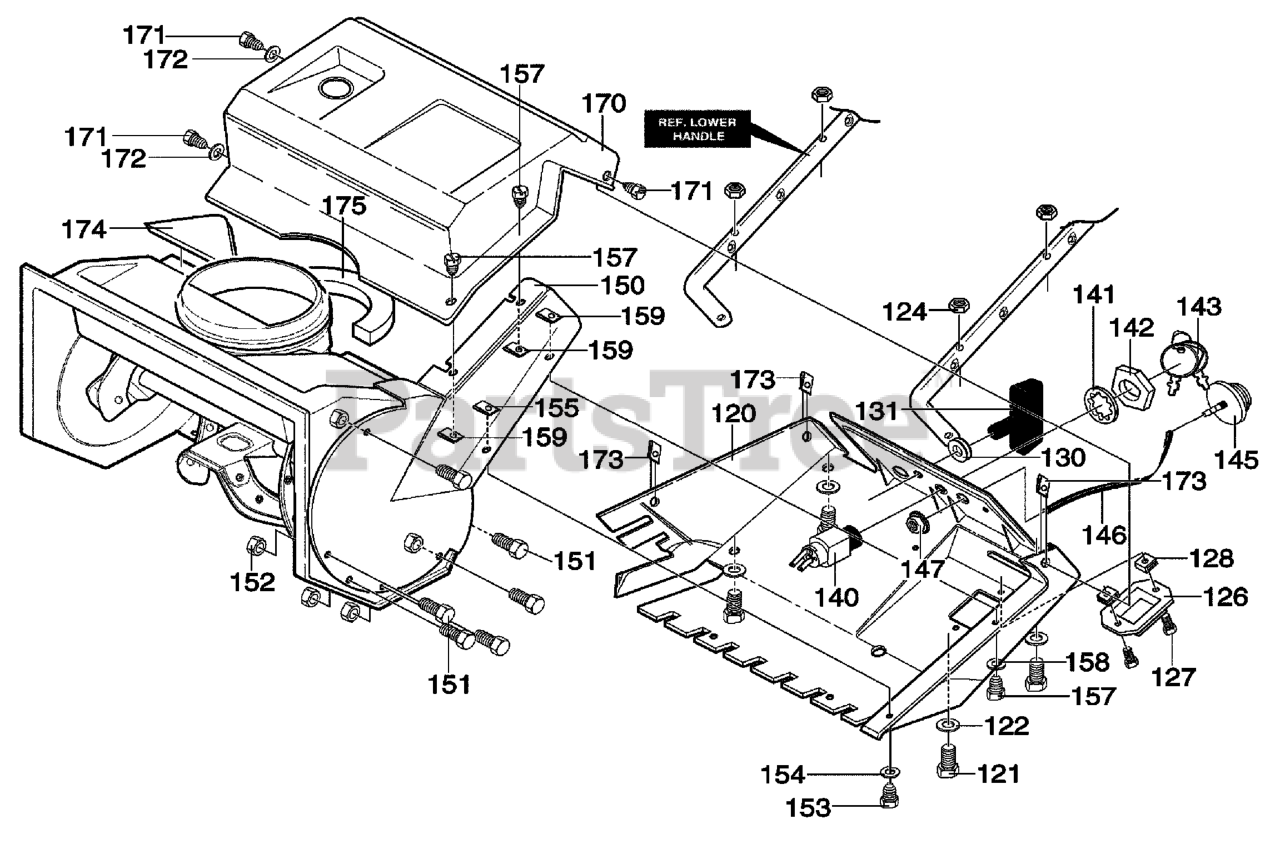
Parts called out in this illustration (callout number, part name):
120	COVER, BOTTOM
121	SCREW, 1/4-20X1.25
122	WASHER, FLAT .281X.63X.065
124	NUT, 1/4-20 REGHEXCTRLK
126	COVER, CARB
127	SCREW, 1/4-14X.75
128	NUT, 1/4-10 SPEED J TYPE
130	GROMMET & WASHER, ROPE GUIDE
131	KNOB, STAND TEE
140	SWITCH, IGNITION
141	WSHER, REGINTLK
142	NUT, 5/8-32 ACC
143	2 KEYS & RING
145	PRIMER, ENGINE
146	HOSE, PRIMER
147	NUT, 1/4-20 REGHEXKEPS
150	COVER, BELT
151	SCREW, 10-24X.50 WAHHMA
152	NUT, #10-24 REGHEXCTRLK
153	SCREW, 1/4-20X.50
154	WASHER, FLAT .281X.63X.065
155	NUT, 1/4-20 TINN
157	SCREW, 1/4-14X.75 SLWATAP
158	WASHER, FLAT .281X.63X.065
159	NUT, 1/4-20 SPEED J TYPE
170	COVER, TOP
171	SCREW, 1/4-14X.75 SLWATAP
172	WASHER, FLAT .281X.63X.065
173	NUT, 1/4-10 SPEED J TYPE
174	SEAL, STRIP AUG HSING FOAM
175	SEAL, STRIP CHUTE & GAS SEAL
